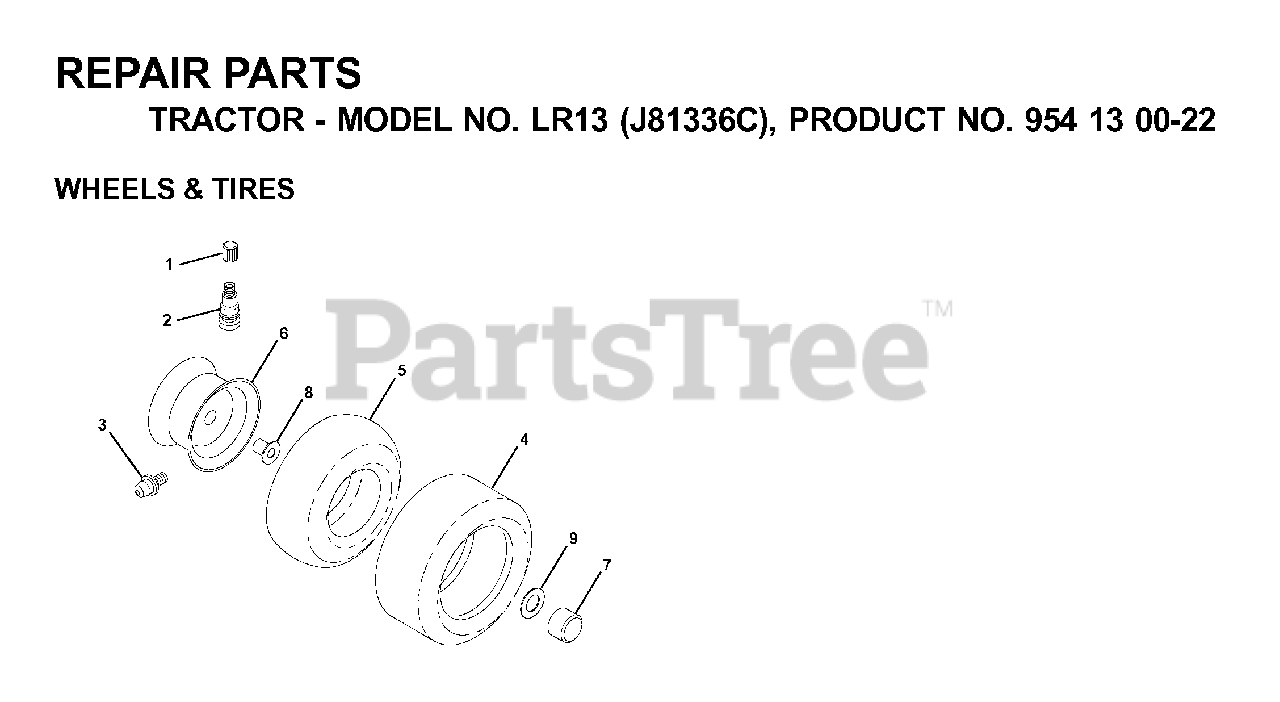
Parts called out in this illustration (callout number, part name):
1	VALVE CAP
2	VALVE STEM LT
3	FITTING LT
4	TIRE FRONT 15X6-6
4	REAR TIRE
5	TUBE.5.3/4.5/6
5	TUBE.16X6.5/7.5-8
6	RIM
6	RIM REAR 8"
7	CAP-HUB FRONT LT
8	BEARING T
